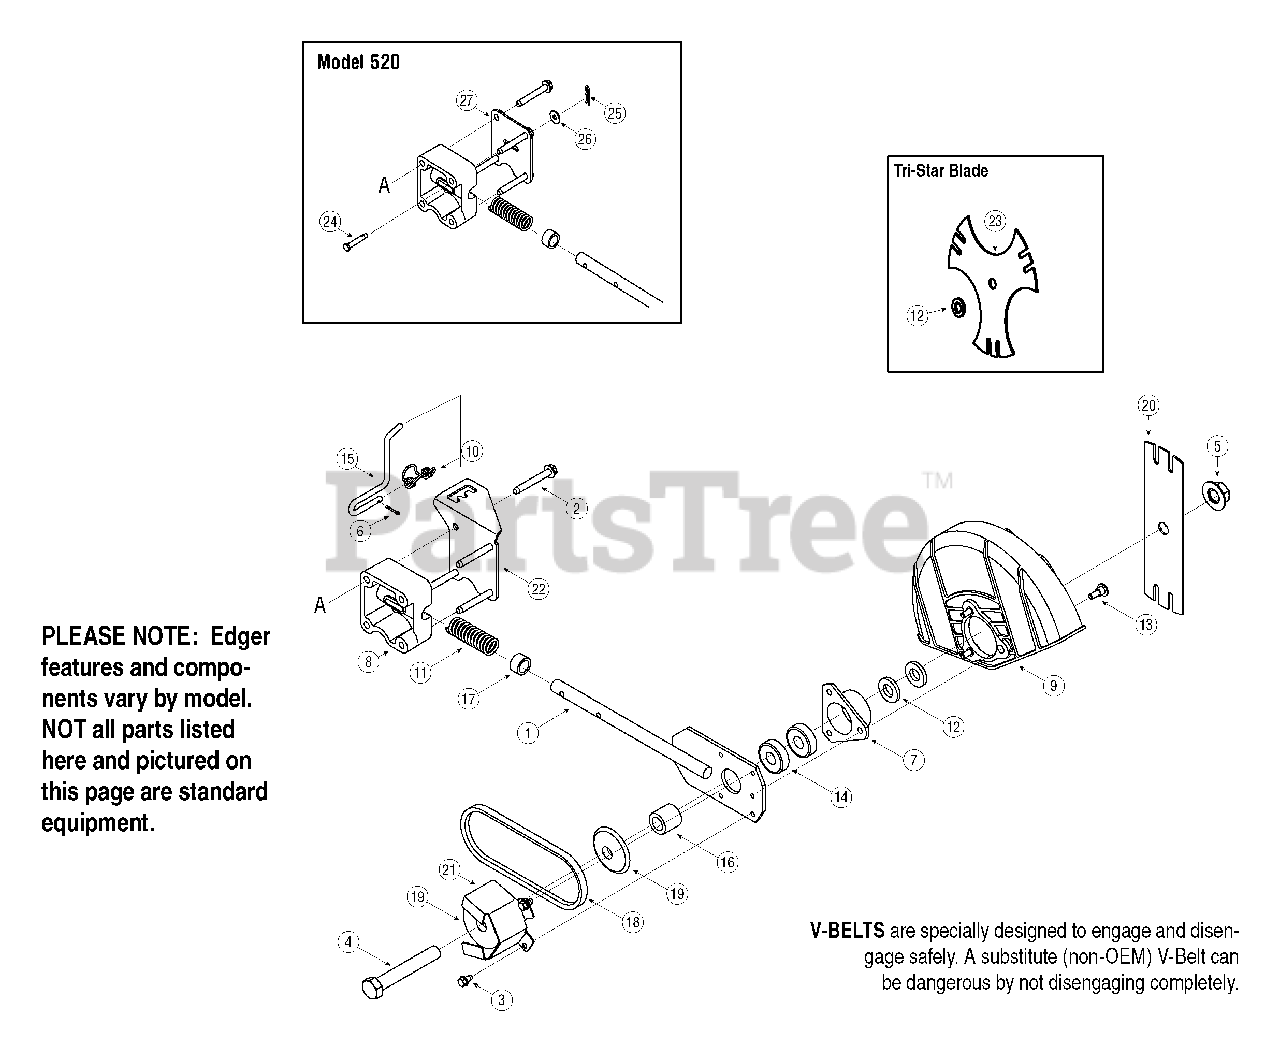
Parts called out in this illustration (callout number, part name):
1	Blade Plate Assembly
2	Hex Screw, 5/16-18
3	Self-tapping Screw, 1/4-20
4	Hex Screw, 5/8-18
5	Flange Nut, 5/8-18
6	Cotter Pin 3/32 x .625
7	Bearing Cup
8	Bearing Block
9	Blade Guard
10	Double Torsion Spring
11	Compression Spring
12	Flat Washer .635x1.24x.181
13	Shoulder Screw
14	Bearing, .625 ID x 1.57 OD
15	Blade Adjustment Rod
16	Spacer, .63 x 1.12 x 1.06
17	Spacer, .64 x.88 x .50
18	Belt
19	Sheave
24	Clevis Pin
25	Cotter Pin
26	Flat Washer, .260 x.72
